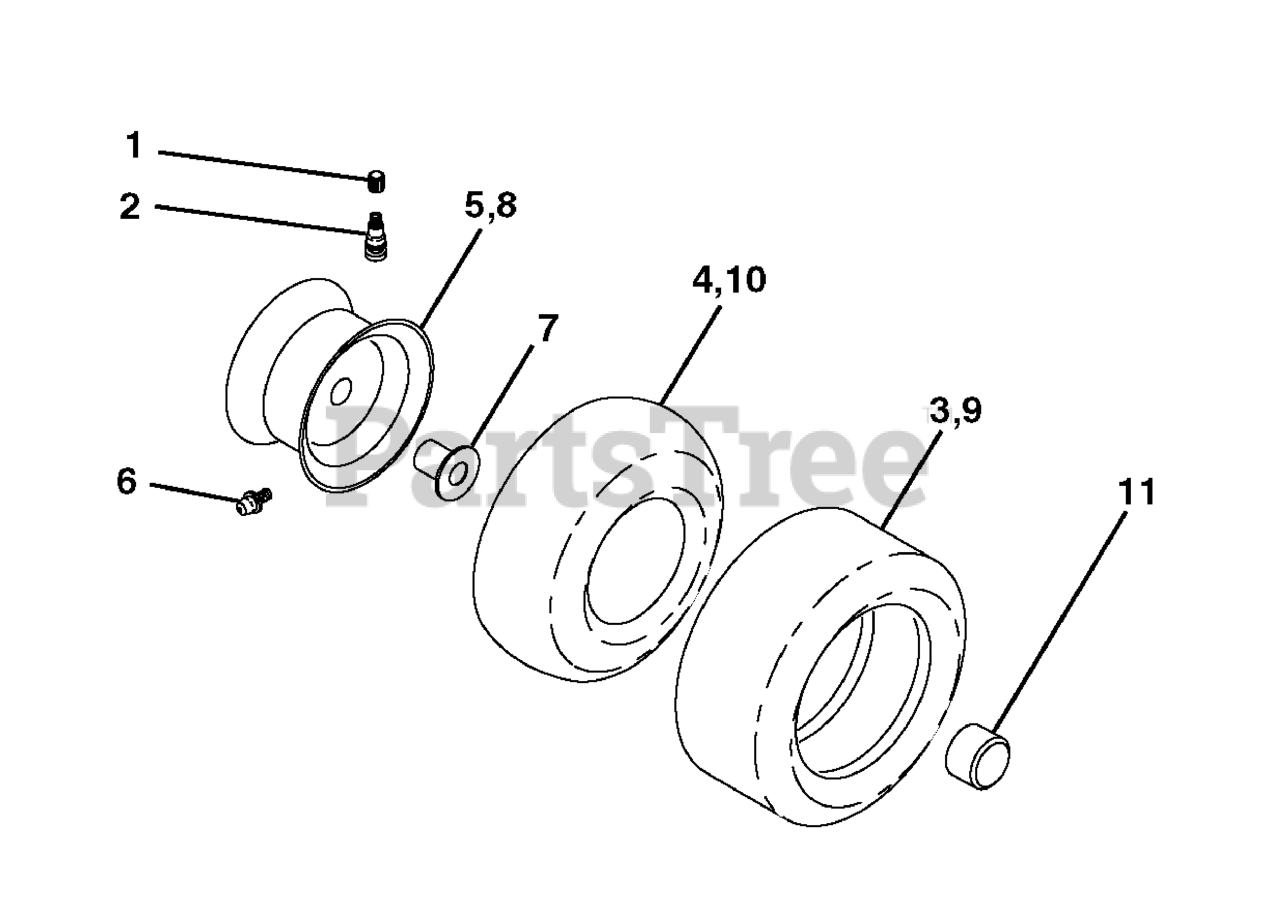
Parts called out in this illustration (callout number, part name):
1	Cap Valve Tire
2	Stem Valve
3	Tire F T 15 x 6 0 - 6 Service
4	Tube Front (Service Item Only)
5	Rim Asm 6" Front Service
6	Fitting Grease (Front Wheel Only)
7	Bearing Flange (Front Wheel Only)
8	Rim Asm 8" Rear Service
9	Tire R 20 x 8-8 Service
10	Tube Rear (Service Item Only)
11	Cap Axle Blk 1 50 x 1 00
